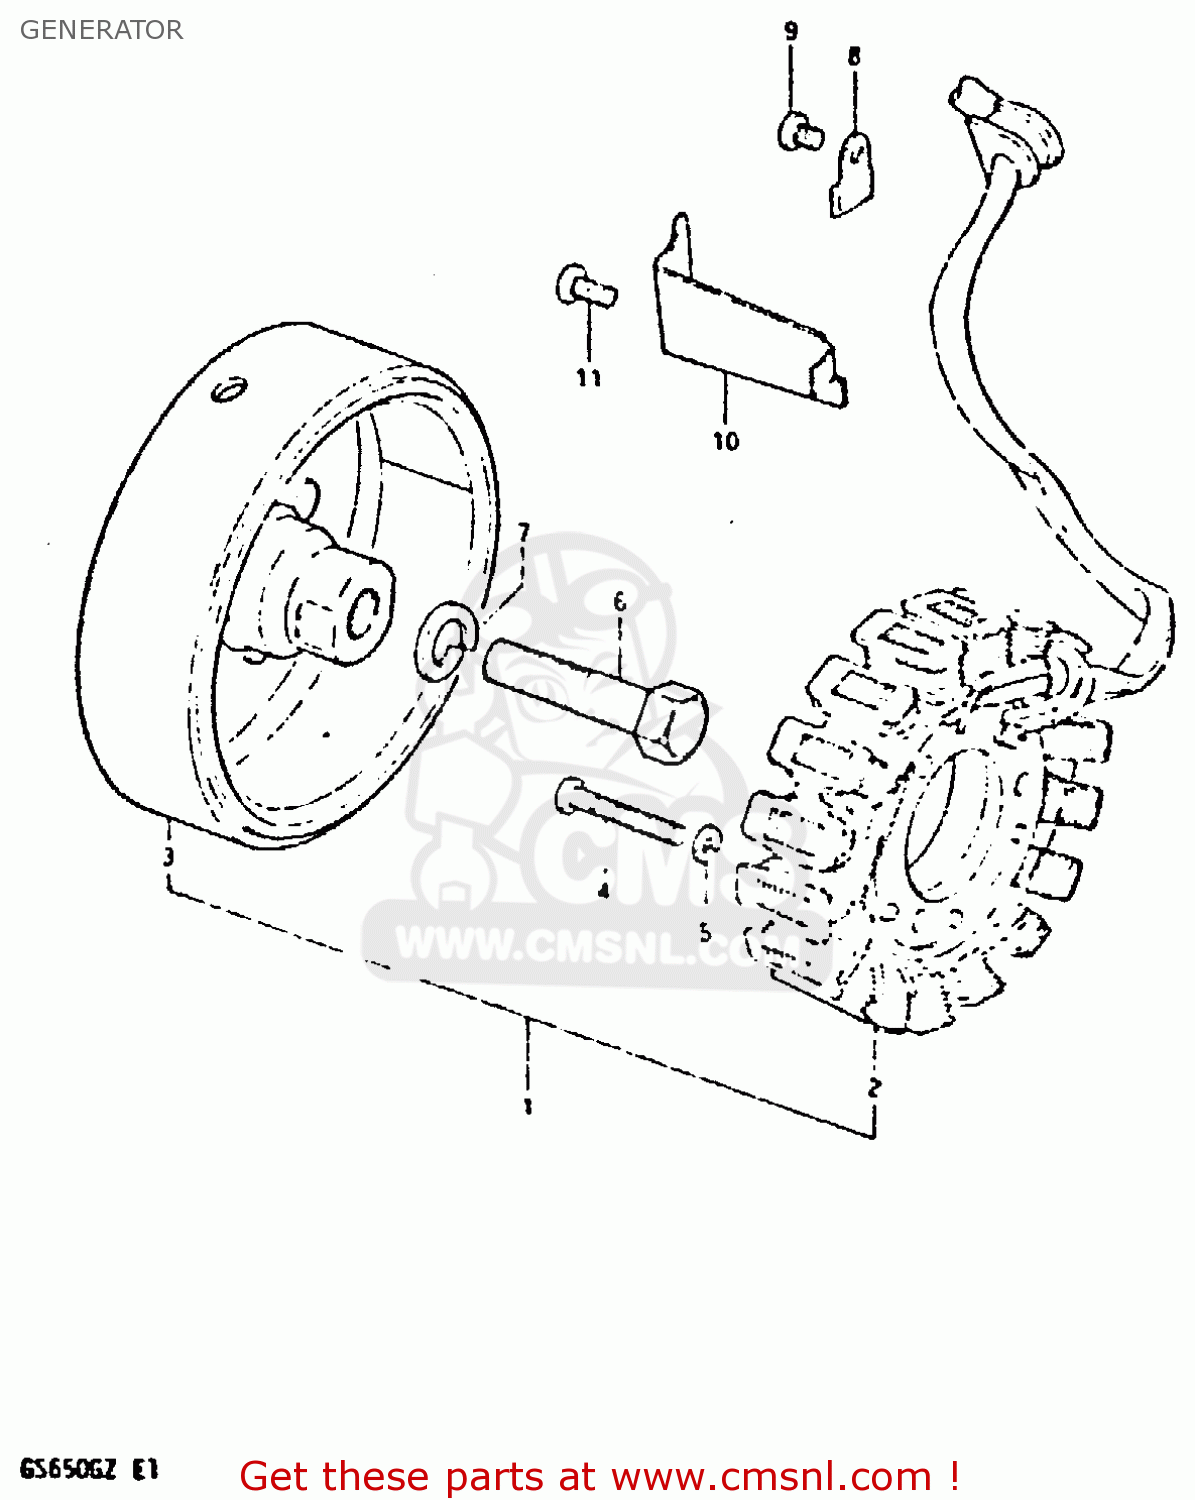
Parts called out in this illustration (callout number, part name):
1	GENERATOR ASSEMBLY
2	STATOR ASSEMBLY
3	ROTOR ASSEMBLY
4	SCREW
5	LOCK WASHER
6	BOLT 12X45
7	WASHER,LOCK 12
8	CLAMP,GENERATOR LEAD WIRE
9	SCREW
10	CLAMP,GENERATOR LEAD WIRE
11	SCREW
